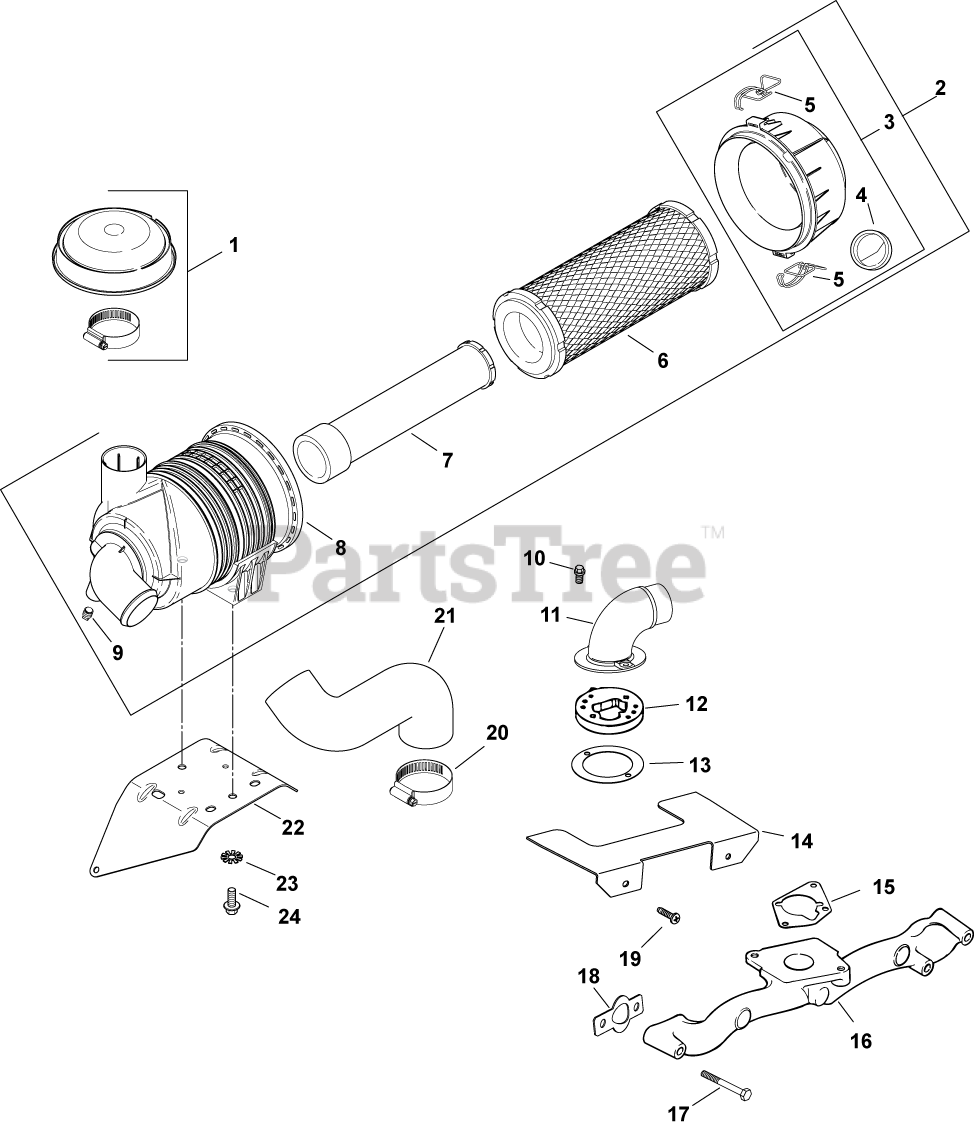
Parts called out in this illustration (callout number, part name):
1	HOOD, AIR CLEANER (5.25)-USE 25 324 04-S
2	AIR CLEANER, CANISTER
3	COVER ASSEMBLY, AIR CLEANER
4	VALVE, DUST EJECTOR
5	CLIP - USE 62 154 07-S
6	ELEMENT, AIR FILTER - PRIMARY
7	ELEMENT, AIR FILTER - SAFETY
8	HOUSING, HEAVY DUTY A/C
9	PLUG, PIPE
10	SCREW, FLG M6X1.0X16
11	ADAPTER, REMOTE AIR CLEANER
12	ADAPTER ASSY (CH18 / 20)-USE 24 029 97-S
13	GASKET, ADAPTER
14	SHIELD, DEBRIS
15	GASKET, AIR CLEANER BASE
16	MANIFOLD, METAL INTAKE
17	SCREW, FLG M6X1.0X55
18	GASKET, INTAKE MANIFOLD USE 24 041 79-S
19	SCREW, PHL HD 11-16X3/4"
20	CLAMP, HOSE
21	HOSE, AIR CLEANER
22	BRACKET, AIR CLEANER
23	WASHER,INT EXT TOOTH LOCK 5/16"
24	SCREW, FLG M8X1.25X20
